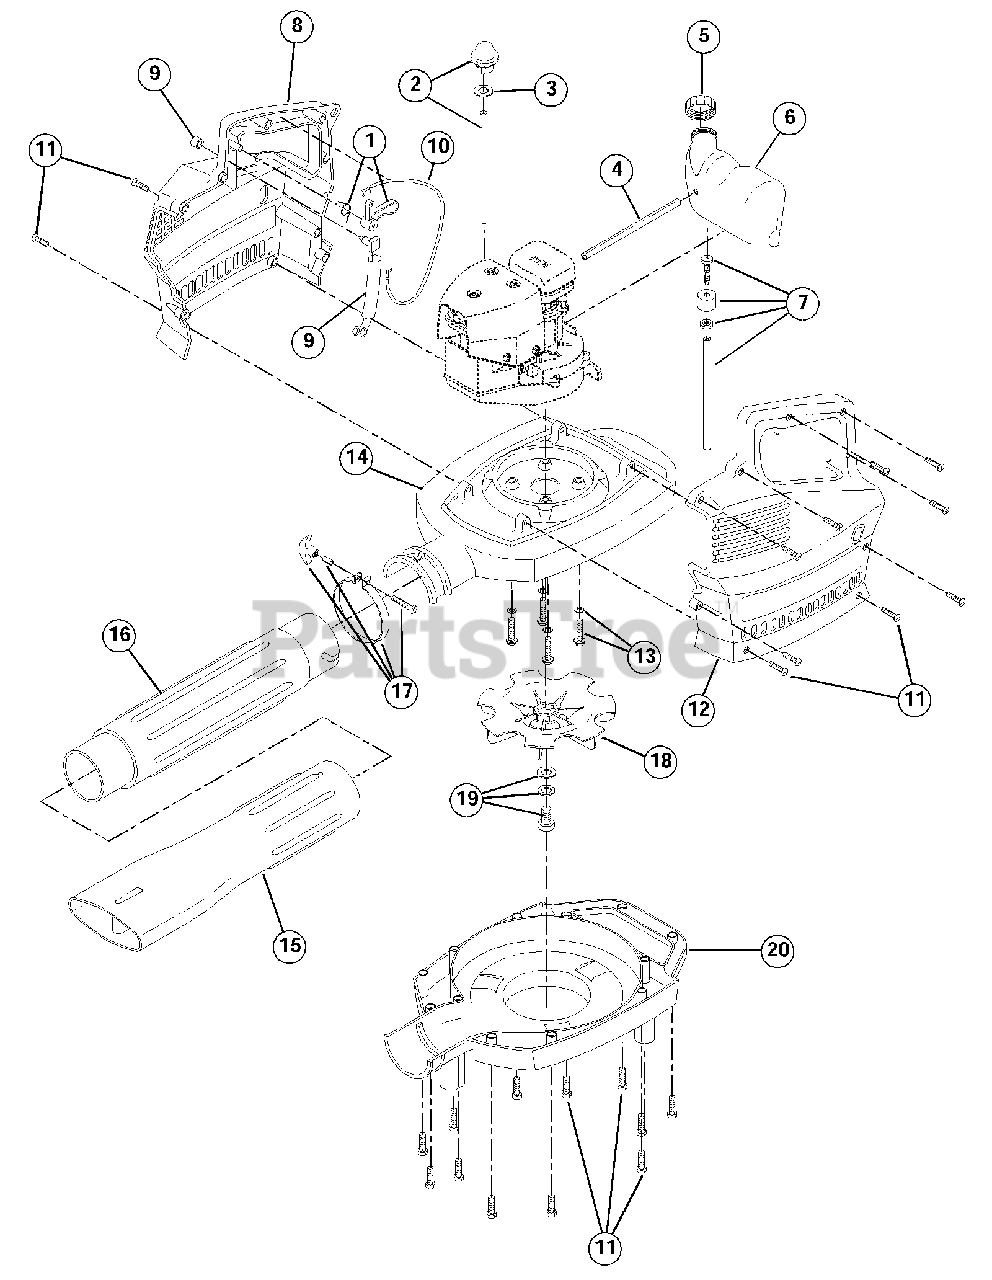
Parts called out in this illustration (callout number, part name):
1	Trigger Assembly
2	Primer Bulb and Hose Assembly
3	Primer Washer
4	Return Line
5	Fuel Cap Assembly
6	Complete Fuel Tank Assembly
7	Fuel Line Assembly
8	R.H. Engine Cover
9	Switch and Lead Assembly
10	Throttle Wire and Housing Assembly
11	Mounting Screw
12	L.H. Engine Cover
13	Mounting Screw Assembly
14	Upper Blower Housing
15	Blower Tube W/Nozzle
16	Blower Tube
17	Clamp Assembly
18	Impeller
19	Mounting Bolt Assembly
20	Lower Blower Housing W/Door
